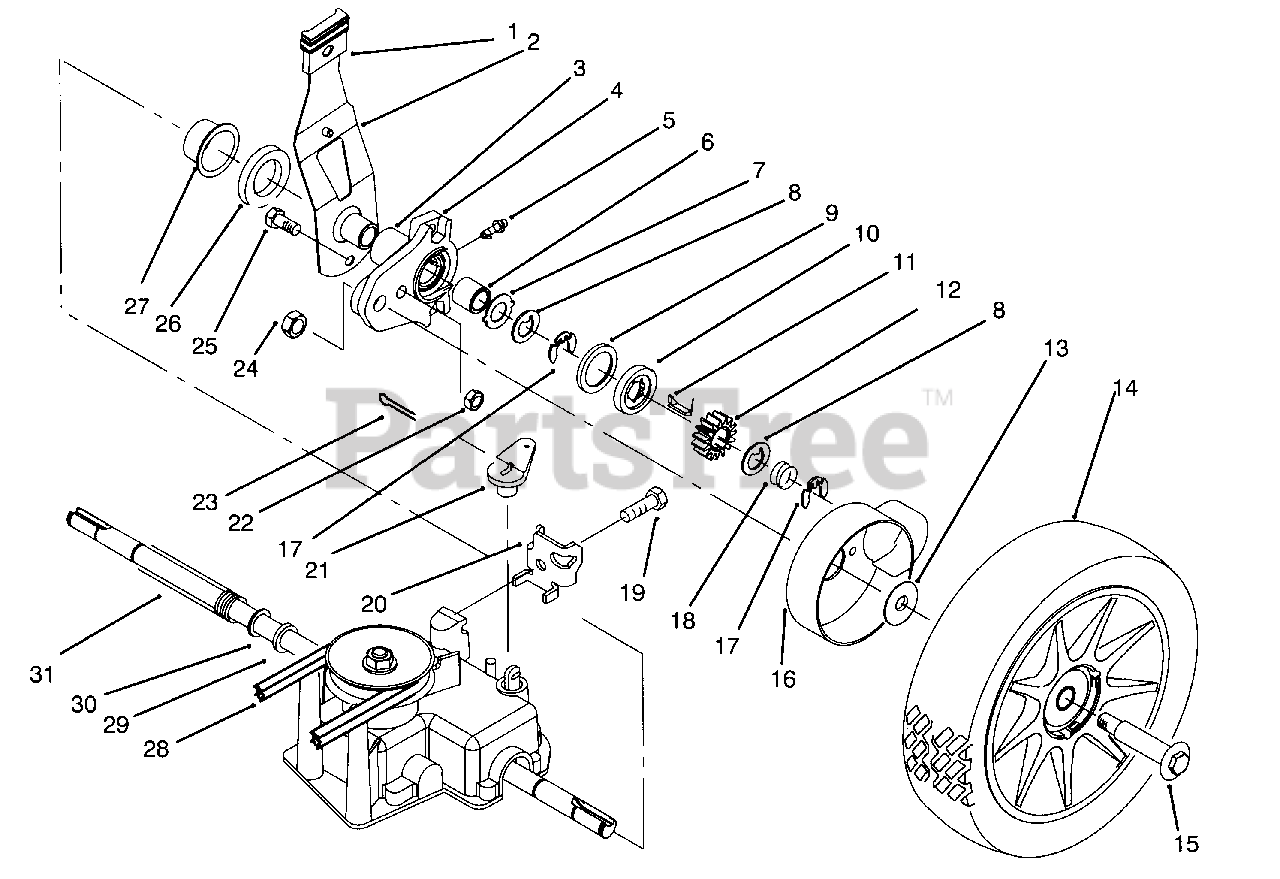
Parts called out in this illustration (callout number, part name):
1	Knob-Spring Arm (Ref.)
2	Spring Arm Assembly
4	Pivot Arm Assembly
5	Fitting-Grease (Ref.)
7	Washer-Thrust
8	Washer-Thrust
9	Ring-Friction
10	Washer-Clutch
11	Key-Rocking, L.H.
12	Gear-Pinion
13	Washer-Stepped
14	Wheel-8"
15	Bolt-Wheel
16	Cover-Wheel
17	Ring-Retaining
18	Spring-Compression
19	Screw-Hex. Hd.
20	Retainer-Cable
21	Lever-Shift
23	Pin-Cotter
26	Spacer-Axle
27	Ring-Isolation
28	"V" Belt
29	Washer-Felt
30	Washer-Flat
31	Cover-Drive Shaft
